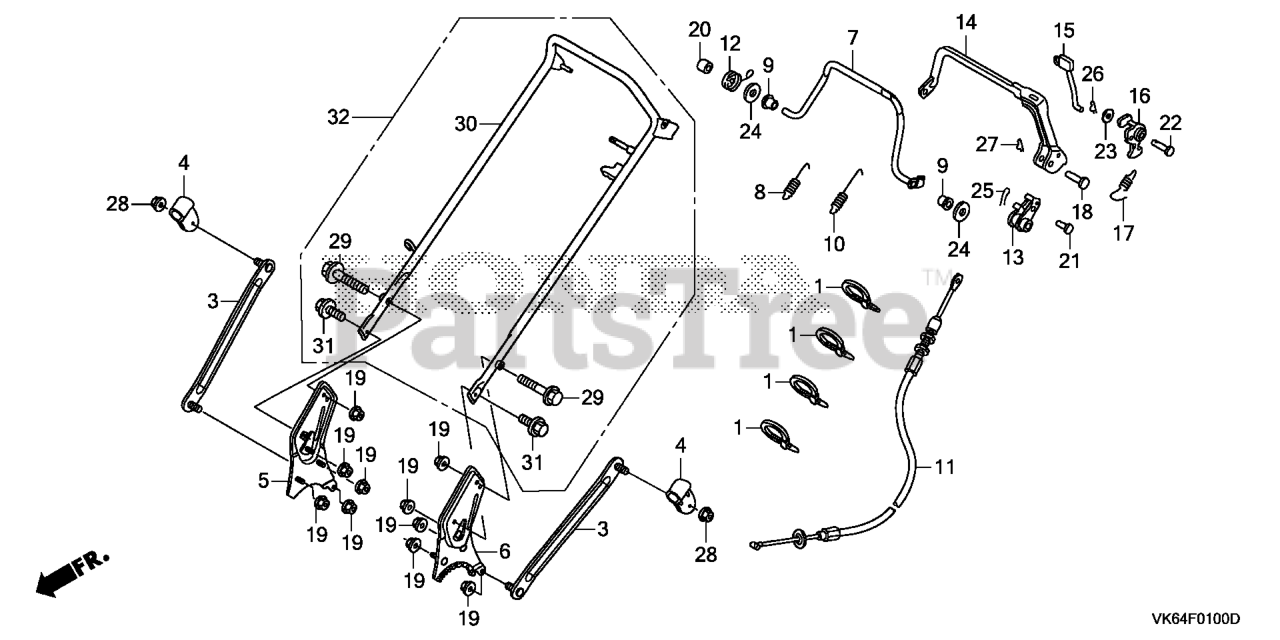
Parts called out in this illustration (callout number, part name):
1	TIE, CABLE
3	PLATE, HANDLE SUPPORT
4	HANGER, HANDLE SUPPORT
5	STAY, R. HANDLE
6	STAY, L. HANDLE
7	LEVER, CLUTCH
8	SPRING, CLUTCH
9	BUSH, CLUTCH LEVER
10	SPRING, CLUTCH LEVER RETURN
11	CABLE, ROTO-STOP
12	SPRING, R. STOP RETURN
13	ARM, ROTO-STOP CABLE
14	LEVER, ROTO-STOP
14	LEVER, ROTO-STOP (FOR U.S.A.)(COO)
15	ROD, RATCHET PUSH
16	LEVER, LOCK
17	SPRING, RATCHET RETURN
18	PIN, CLUTCH LEVER
19	NUT, SELF-LOCK (8MM)
20	COLLAR (8X11X13.5)
21	PIN, CABLE JOINT
22	PIN, LOCK LEVER HINGE (6X30)
23	WASHER, PLAIN (6MM)
24	WASHER, PLAIN (8MM)
25	PIN, COTTER (1.6X12)
26	PIN, LOCK (6MM)
27	PIN, LOCK (8MM)
28	NUT, SELF-LOCK (8MM)
29	BOLT, FLANGE (8X40) Use up to Engine SN 1003236.
30	PIPE, HANDLE *NH105* (MAT BLACK)
31	BOLT, FLANGE (8X16) Use from Engine SN 1000016.
31	BOLT, FLANGE (8X40) Use up to Engine SN 1003236.
32	PIPE KIT, HANDLE
